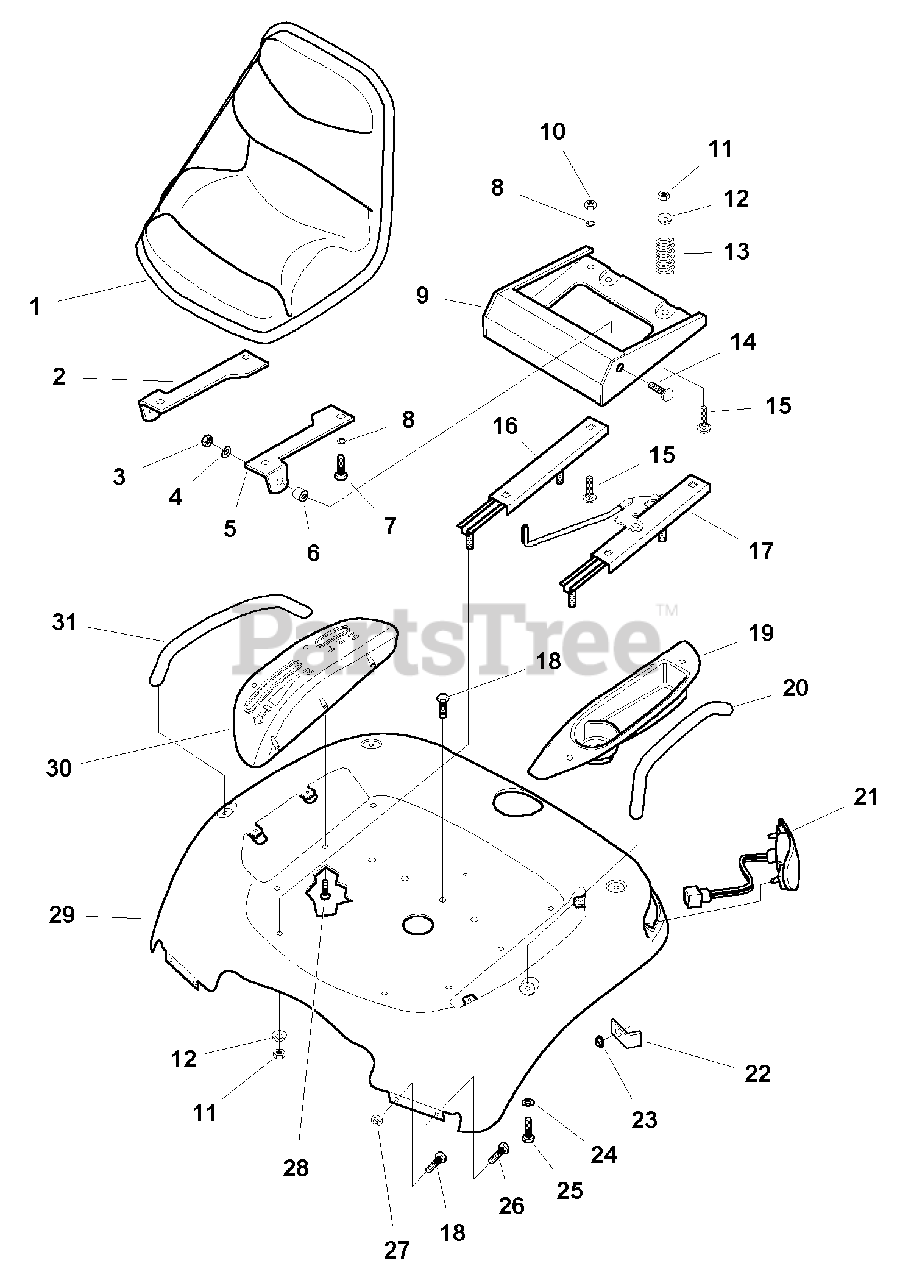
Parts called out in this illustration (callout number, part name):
2	SEAT BRACKET, RH
3	NUT, Hex Nylock, 3/8-16
4	WASHER, 13/32
5	SEAT BRACKET, LH
7	CAPSCREW, 1/4-20 x 5/16
8	LOCKWASHER, 5/16
9	BRACKET, Seat Support
10	NUT, Hex, 5/16-18
11	NUT, Hex Nylock, 5/16-18
12	WASHER, Bell
13	SPRING, Seat
14	CARRIAGE BOLT, 3/8-16 x 1
15	CARRIAGE BOLT, 5/16-18 x 3/4
16	SLIDER ASSEMBLY, RH, Slave
17	SLIDER ASSEMBLY, LH, Main
18	CAPSCREW, Hex Head, Taptite, 5/16-18 x 3/4
19	CUPHOLDER POD
21	TAIL LIGHT, Assembly
23	PUSHNUT, 5/16
24	WASHER, 5/16
25	CAPSCREW, 5/16-18 x 1/2
26	CAPSCREW, Hex Flange, 5/16-18 x 1/2
27	NUT, WhizWhizlock 5/16-18
28	CAPSCREW, #10 x 5/16
29	SEAT DECK (Orange)
29	SEAT DECK (Red)
30	CONTROL POD
